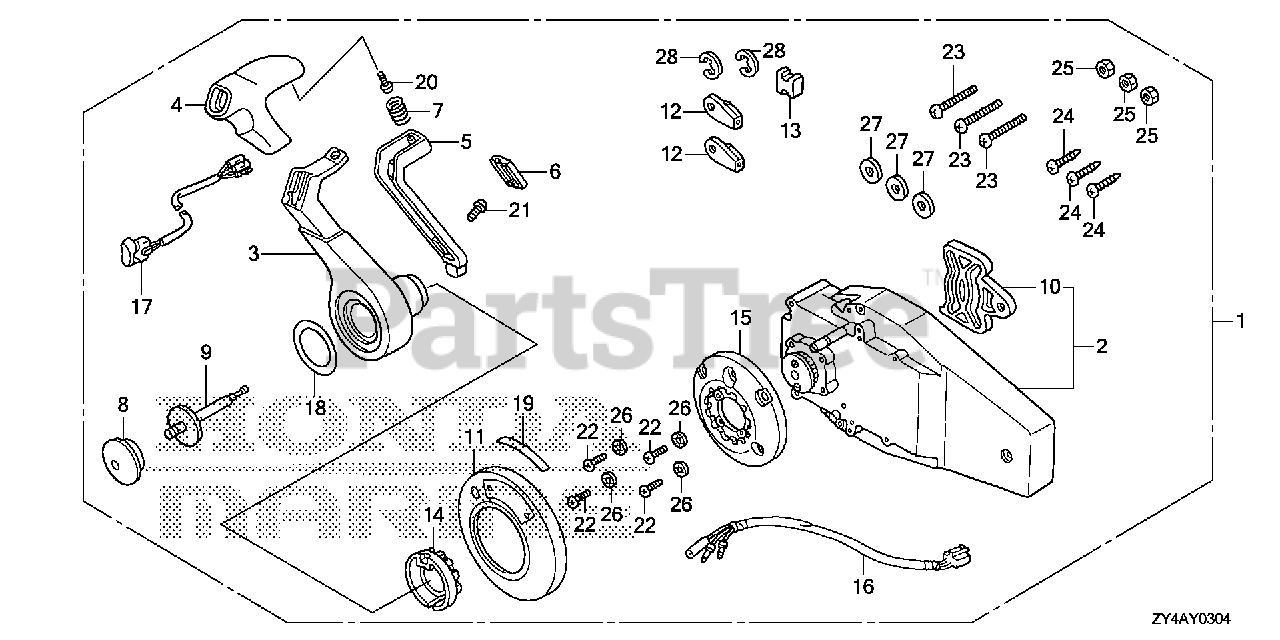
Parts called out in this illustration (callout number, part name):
1	BOX KIT, REMOTE CONTROL (FLUSH MOUNT)(R)
2	HOUSING ASSY., R. (INNER) (FLUSH MOUNT)
3	HANDLE, REMOTE CONTROL
4	COVER, GRIP
5	ARM, NEUTRAL LOCK
6	COVER, LOCK ARM
7	SPRING, NEUTRAL LOCK ARM
8	BUTTON, THROTTLE
9	SHAFT, THROTTLE BUTTON
10	PLATE, DWELL
11	COVER ASSY.
12	TERMINAL, CABLE
13	SPACER, CABLE CLAMP
14	HOLDER, NEUTRAL LOCK
15	BASE
16	SUB-HARNESS ASSY., POWER TRIM-TILT (C)
17	SWITCH ASSY., POWER TRIM-TILT (C)
18	MARK, HANDLE FLUSH MOUNT
19	MARK, FLUSH MOUNT
20	SCREW, PAN (5X16)
21	SCREW, TRUSS (4X12)
22	SCREW, PAN (5X30)
23	SCREW, PAN (6X35)
24	SCREW, TAPPING (6X30)
25	NUT, HEX. (6MM)
26	WASHER, LOCK (5MM)
27	WASHER, PLAIN (6MM)
28	E-RING (6MM)
